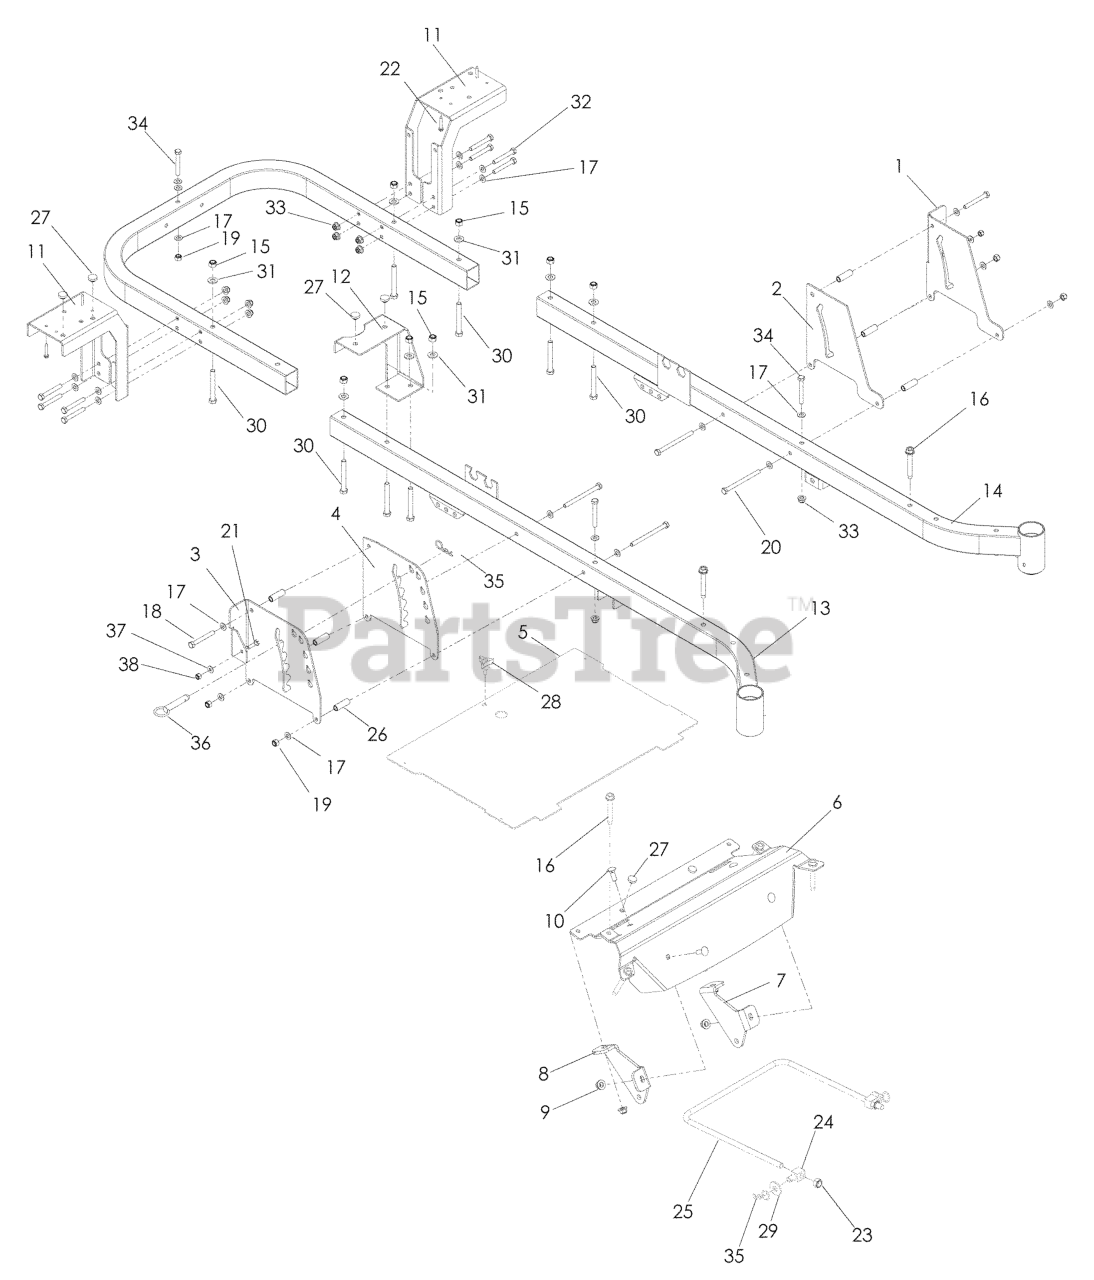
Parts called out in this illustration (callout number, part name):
1	PLATE, OUTER BRAKE
2	PLATE, BRAKE LATCH
3	PLATE, DECK HEIGHT
4	PLATE, DECK HEIGHT
5	FOOT PLATE w/DECALS
7	MOUNT, STRUT, RT, BLK
8	MOUNT, STRUT, LT, BLK
9	NUT 3/8-16 HEX FLG NYLOC
10	RHSNB 3/8-16 x 1
11	SUPPORT, FENDER
12	SUPPORT, TANK
13	FRAME, FRONT RT
14	FRAME, FRONT LT
15	NUT 3/8-16 HEX NYLOC
16	BOLT 3/8-16 x 25/8 THD FRM
17	WASHER 5/16 SAE FLAT
18	HCS 5/16-18 x 2½
19	NUT 5/16-18 HEX NYLOC
20	HCS 5/16-18 x 4
21	HCS ¼-20 x 1
22	SCREW 10-12 x 1¼ WSH HD
23	NUT 7/16-14 HEX NYLOC
25	LINK, FRONT SUSPENSION
26	SPACER ½ OD x 1½
27	GROMMET, BUMPER
28	KNOB w/STUD
29	WASHER ½ FLAT
30	HCS 3/8-16 x 3
31	WASHER 3/8 SAE FLT
32	HCS 5/16-18 x 2¼
33	NUT 5/16-18 FLANGE NYLOC
34	HCS 5/16-18 x 2¾
35	#4 HAIRPIN
37	WASHER ¼ FLAT SAE
38	NUT ¼-20 HEX NYLOC
